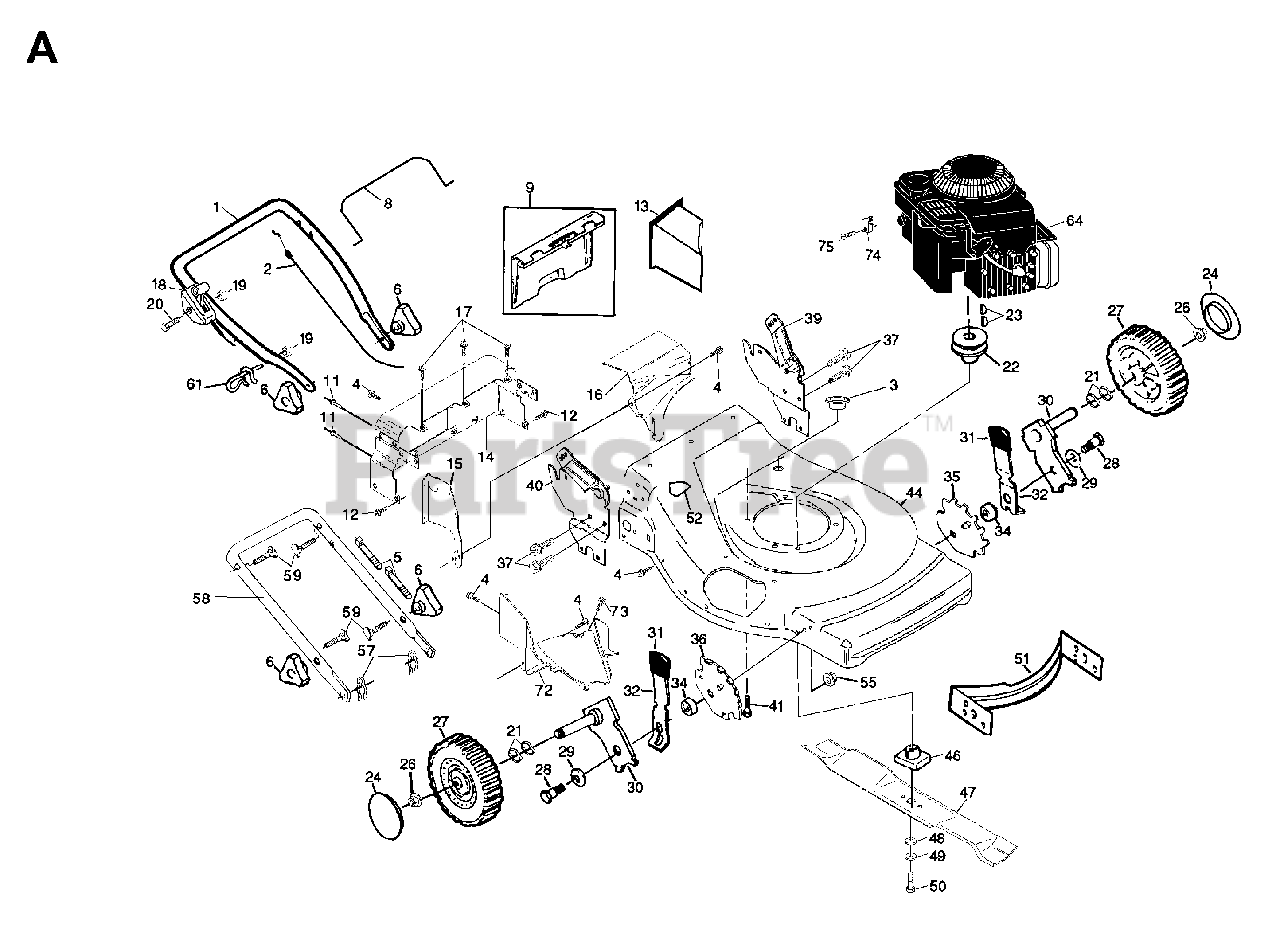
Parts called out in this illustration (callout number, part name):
2	CABLE-ZONE
4	SCREW.HXTAP.10-24
5	TIE GUIDE
6	HANDLE KNOB
8	CONTROL BAR
11	RIVET BLIND
13	MULCHER PLUG
15	SIDE BAFFLE
16	DISCHARGE BAFFLE
18	THROTTLE CONTROL
19	NUT
20	SCREW 1/4-20X1.75
21	WAVE WASHER
22	ENGINE.PULLEY.FWG
23	HI PRO KEY PM
24	CAP.HUB.ARC.SPOKE.8".LP
26	HEX FLANGE LOCKNT
27	WHEEL.8X2.PR.LP.RAD.GREY
28	BOLT
29	BELLEVILLE WASHER
30	AXLE ARM
31	SELECTOR KNOB
32	SELECTOR SPRING
34	RP SPACER HT ADJ
37	SELF-TAPPING SCREW 5/16-18X3/4
41	BOLT 3/8-16X1-1/8
46	RP BLADE ADAPTOR
47	%BLADE, MULCH
48	WASHER,HARDEN
49	LOCKWASHER
50	SCREW, HEX HD 3/8-24 X 1-3/8
52	DECAL MOWER CUT/FINGER
55	LOCKNUT PM
57	HAIRPIN COTTER
59	HANDLE BOLT
61	ROPE GUIDE
72	BAFFLE BELT COVER
73	SCREW.HX.13X.750
75	SCREW.HEX.HEAD.WASHER.10-16
